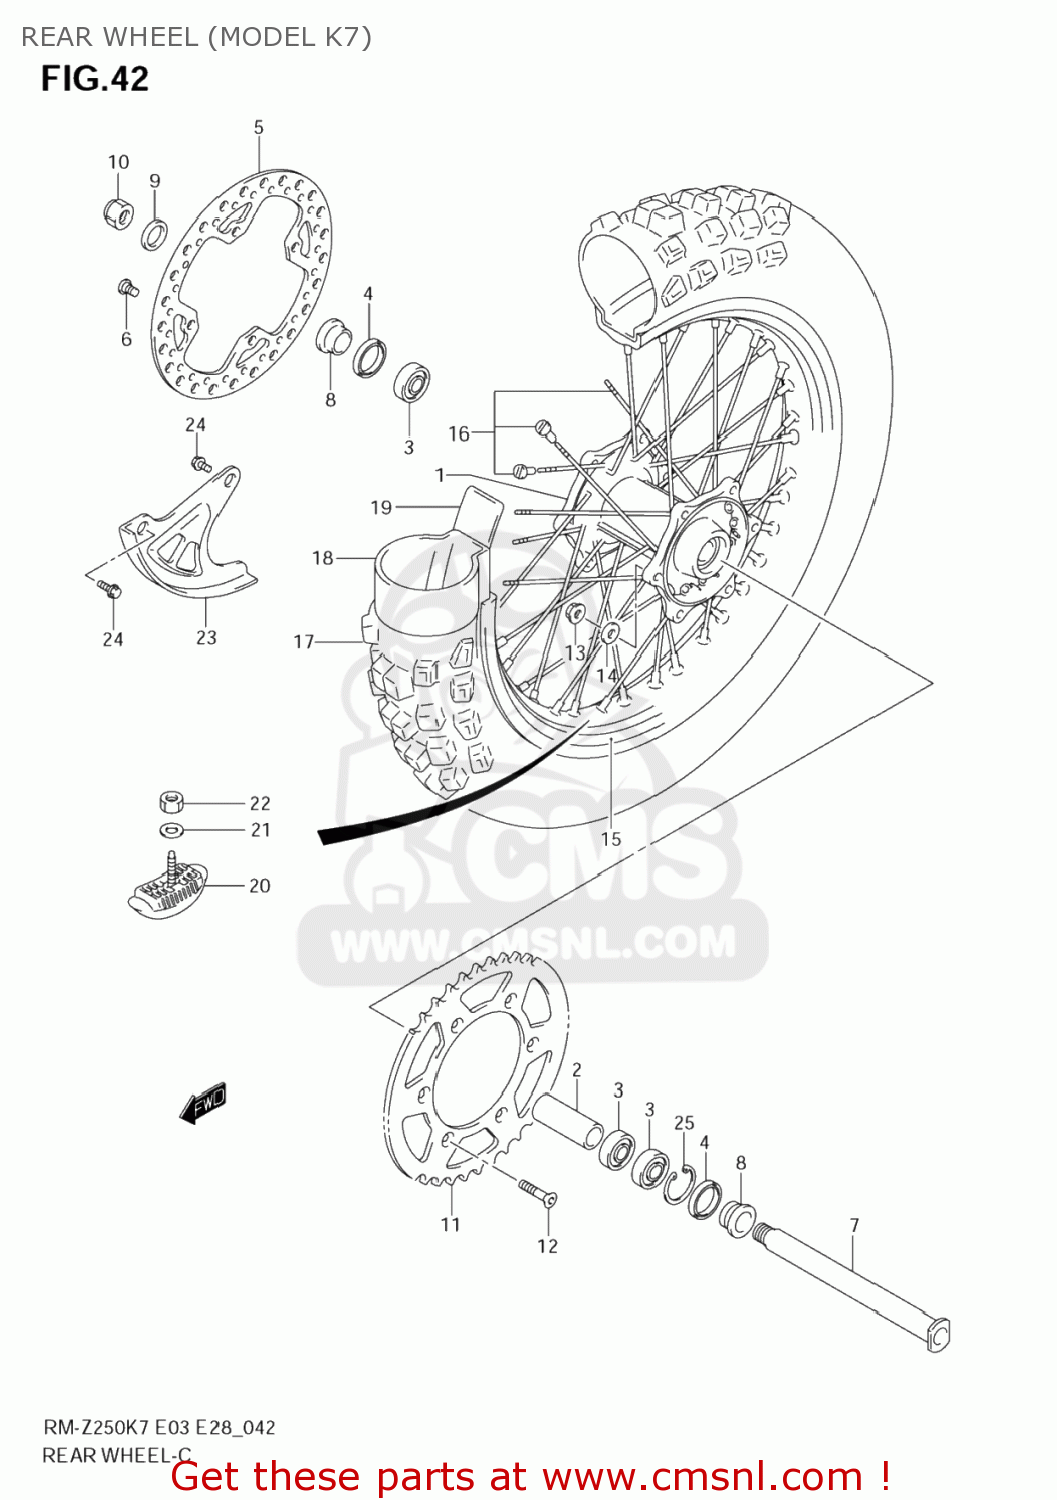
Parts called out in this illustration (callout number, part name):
1	HUB,RR
2	SPACER,RR HUB BEARING
3	BEARING(25X42X9)
4	SEAL,OIL(32X43X7)
5	DISC,RR BRAKE
6	SCREW(8X15)
7	AXLE,REAR
8	SPACER,REAR AX
9	WASHER(22X35X2)
10	NUT
11	SPROCKET,RR(NT:48)
12	BOLT(8X28)
13	NUT
14	WASHER(8.5X16X1.2)
15	RIM,RR WHEEL(19X1.85 AL)(WHT)
16	SPOKE SET,RR WHEEL
17	TIRE,RR(100/90 19)
18	TUBE
19	PROTECTOR,WHL INR TUBE
20	STOPPER,BEAD(1.85)
21	WASHER
22	NUT
23	COVER,REAR DIS
24	BOLT(6X12)
25	CIRCLIP
